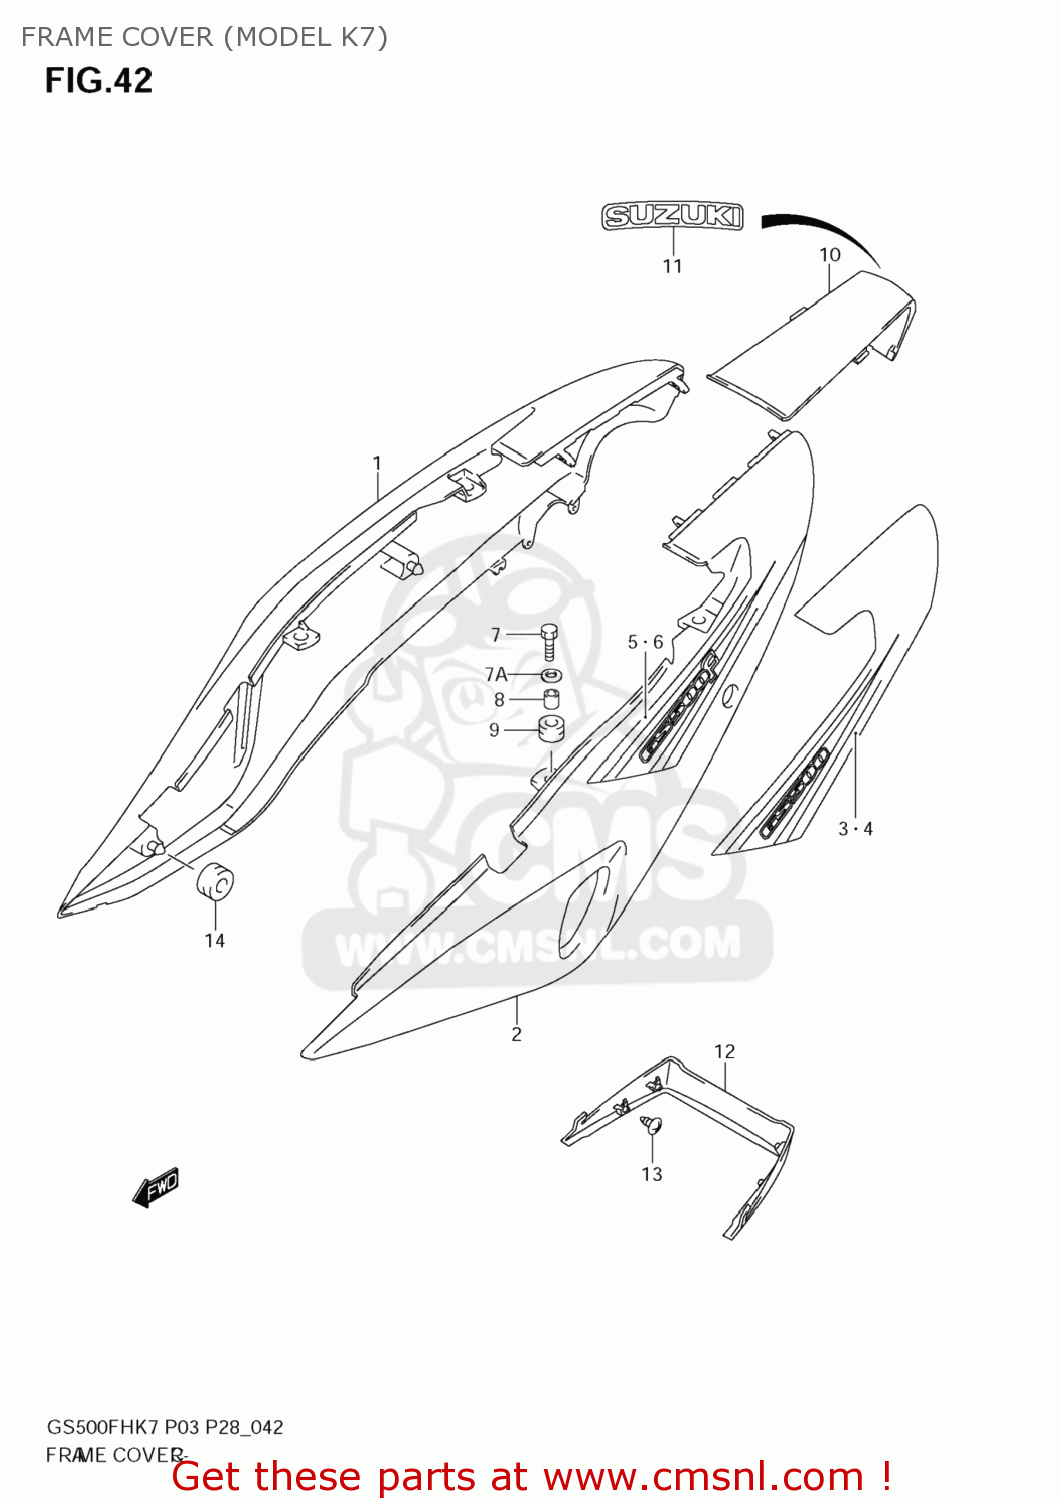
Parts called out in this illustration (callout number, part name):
1	COVER FRAME WHITE
2	COVER, FRAME G
3	TAPE,FRAME COVE
4	TAPE,FRONT COVE
5	TAPE, RH
6	TAPE,FRAME COV
7	BOLT
7A	WASHER
8	SPACER(6.5X9X9)
9	CUSHION
10	FAIRING PART
11	TAPE,FRAME COVE
12	COVER, LOWER
13	SCREW
14	CUSHION
